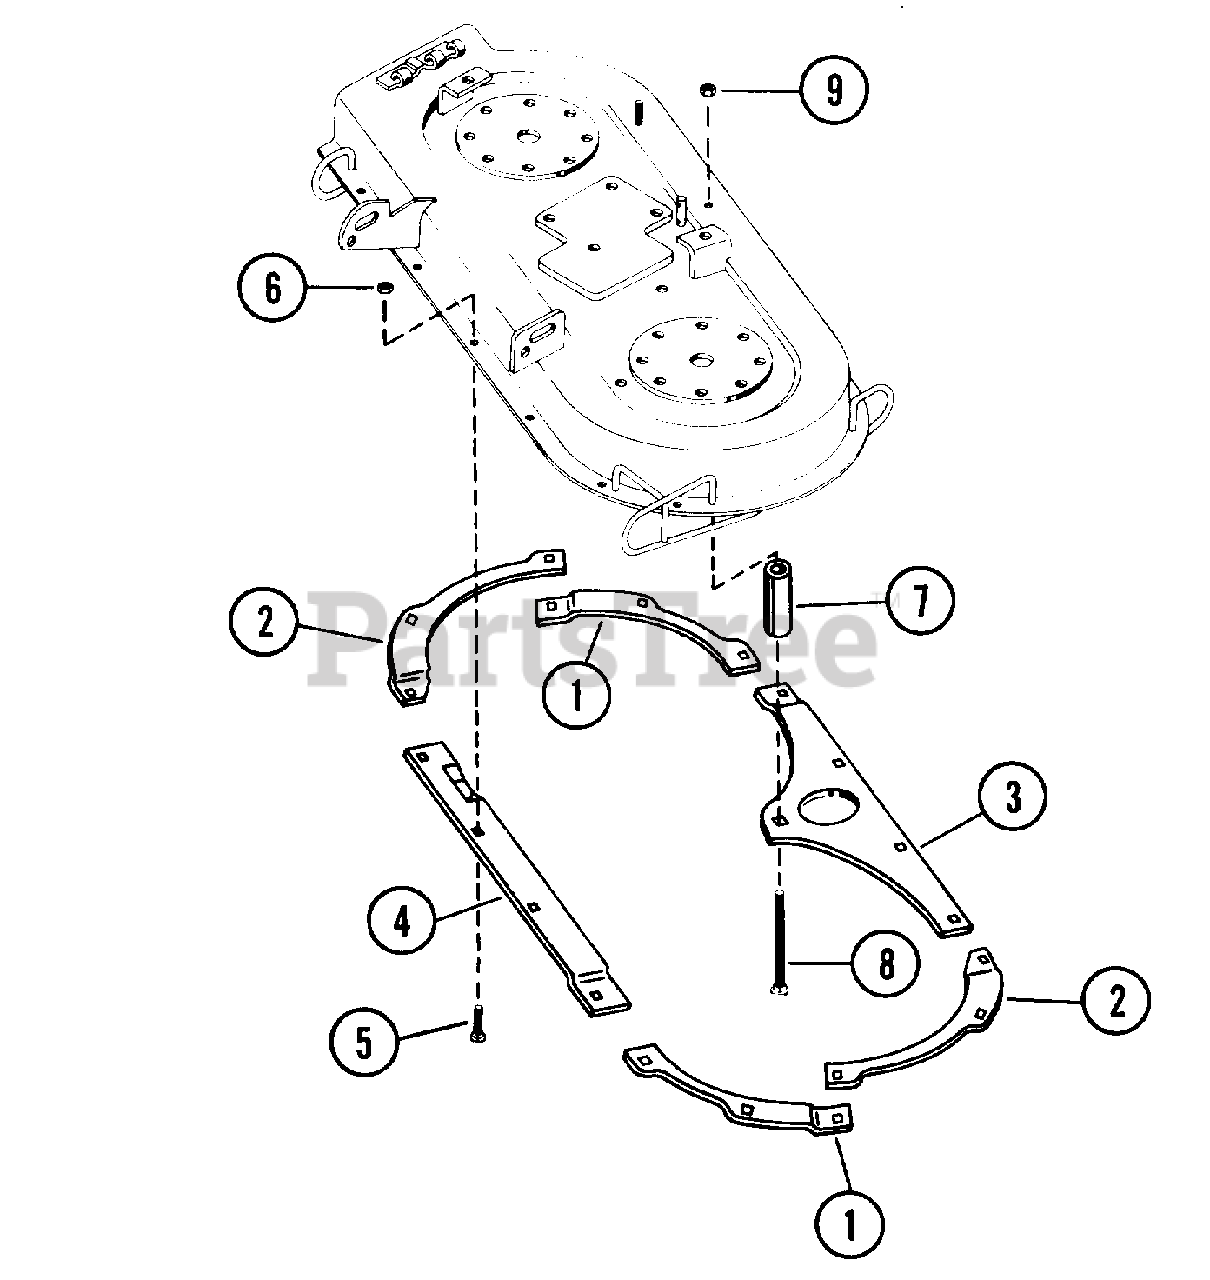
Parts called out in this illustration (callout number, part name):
1	FLANGE, SHORT CURVE
2	FLANGE, LONG CURVE
3	FLANGE, REAR
4	FLANGE, FRONT
5	BOLT, 1/4-20X.625 RD HD SQ NK
6	NUT, LOCK 1/4-20
7	SPACER
8	BOLT, 1/2-13X4.25 RD HD SQ NK
9	NUT, LOCK 1/2-13
